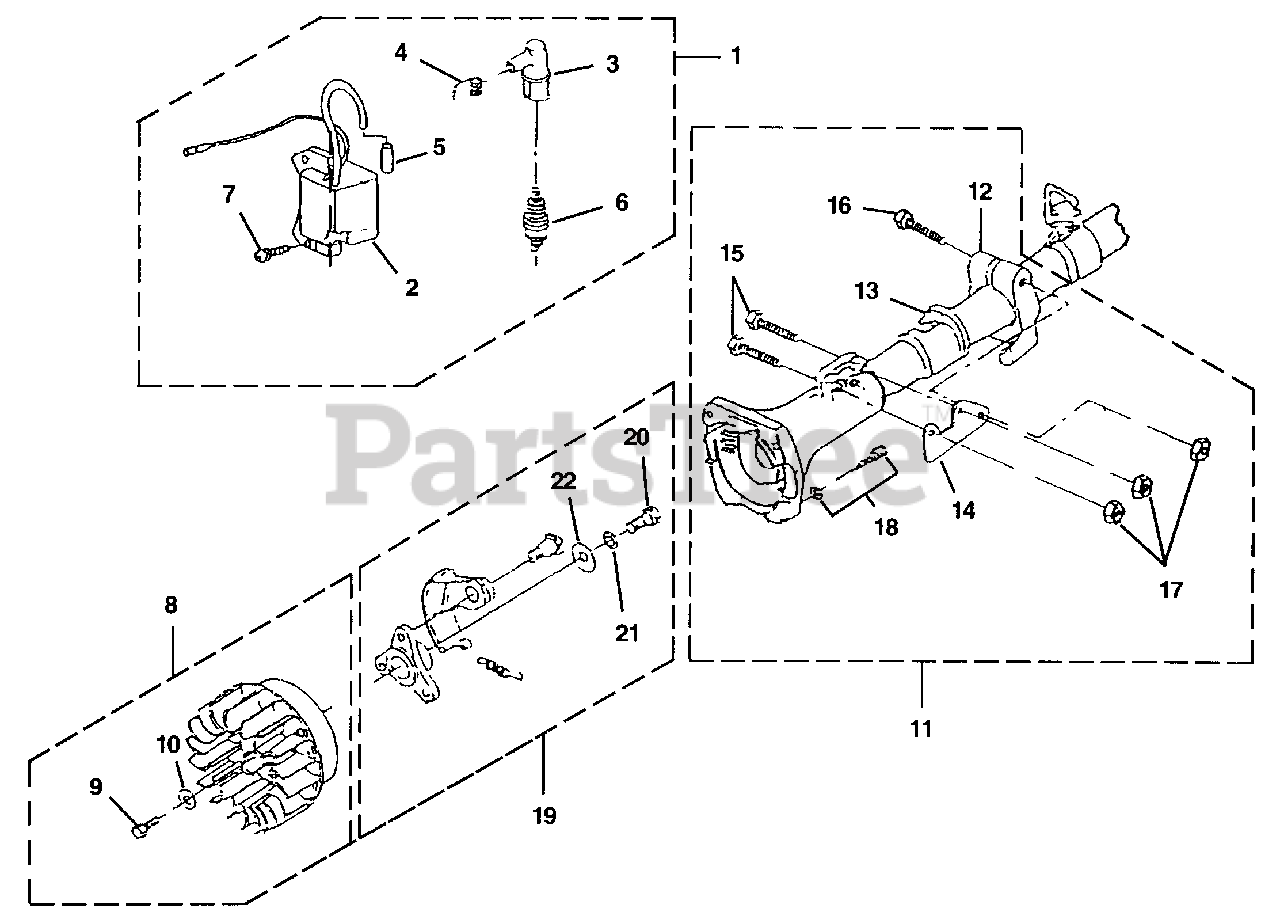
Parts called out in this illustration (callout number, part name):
1	IGNITION KIT
2	MODULE - Ignition
3	CAP - Plug
4	SPRING - Plug Cap
6	SPARK PLUG
7	SCREW-Socket Hd (M5 x 22 W)
8	ROTOR ASSEMBLY
9	BOLT
11	CLUTCH HOUSING
18	SCREW - Socket Hd (M6 x 18 SW)
19	CLUTCH ASSEMBLY
20	BOLT
21	WASHER - Spring
